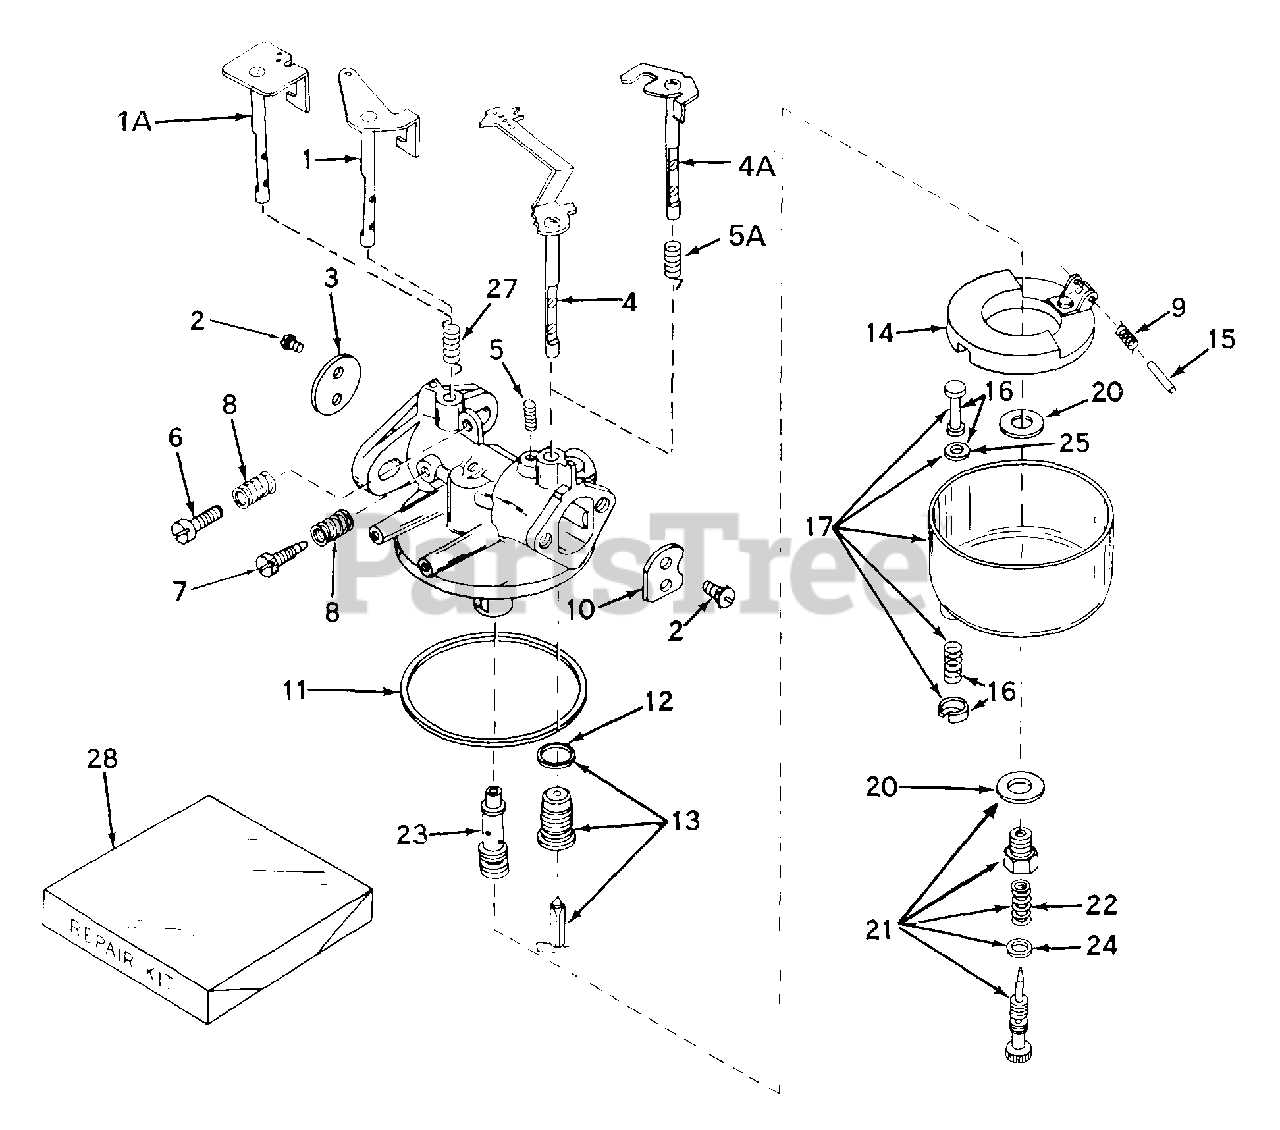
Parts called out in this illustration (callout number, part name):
1	"Shaft & Lever Assy., Throttle
2	Screw, Pan hd. Sems, 4-40 x 3/16
3	Shutter, Throttle
4	Shaft & Lever Assy., Choke
5	Spring, Choke stop
6	Screw, Throttle adjusting
7	Needle, Idle adjusting
8	Spring, Adjusting needle
9	Spring, Float shaft
10	Shutter, Choke
11	Gasket, Bowl-to-body
12	Gasket, Valve seat
13	Valve, Seat, Gasket & Spring Assy. (. 083
15	Shaft, Float
16	Drain Assy., Bowl (Incl. No. 25).
17	Bowl & Drain Assy. (Incl. No. 16)
20	Gasket, Bowl-to-body
21	Needle Assy., Power adjusting
22	Spring, Adjusting needle
23	Nozzle, Main
24	"O" Ring
25	Gasket, Drain stem
27	Spring, Throttle return
28	Repair Kit
